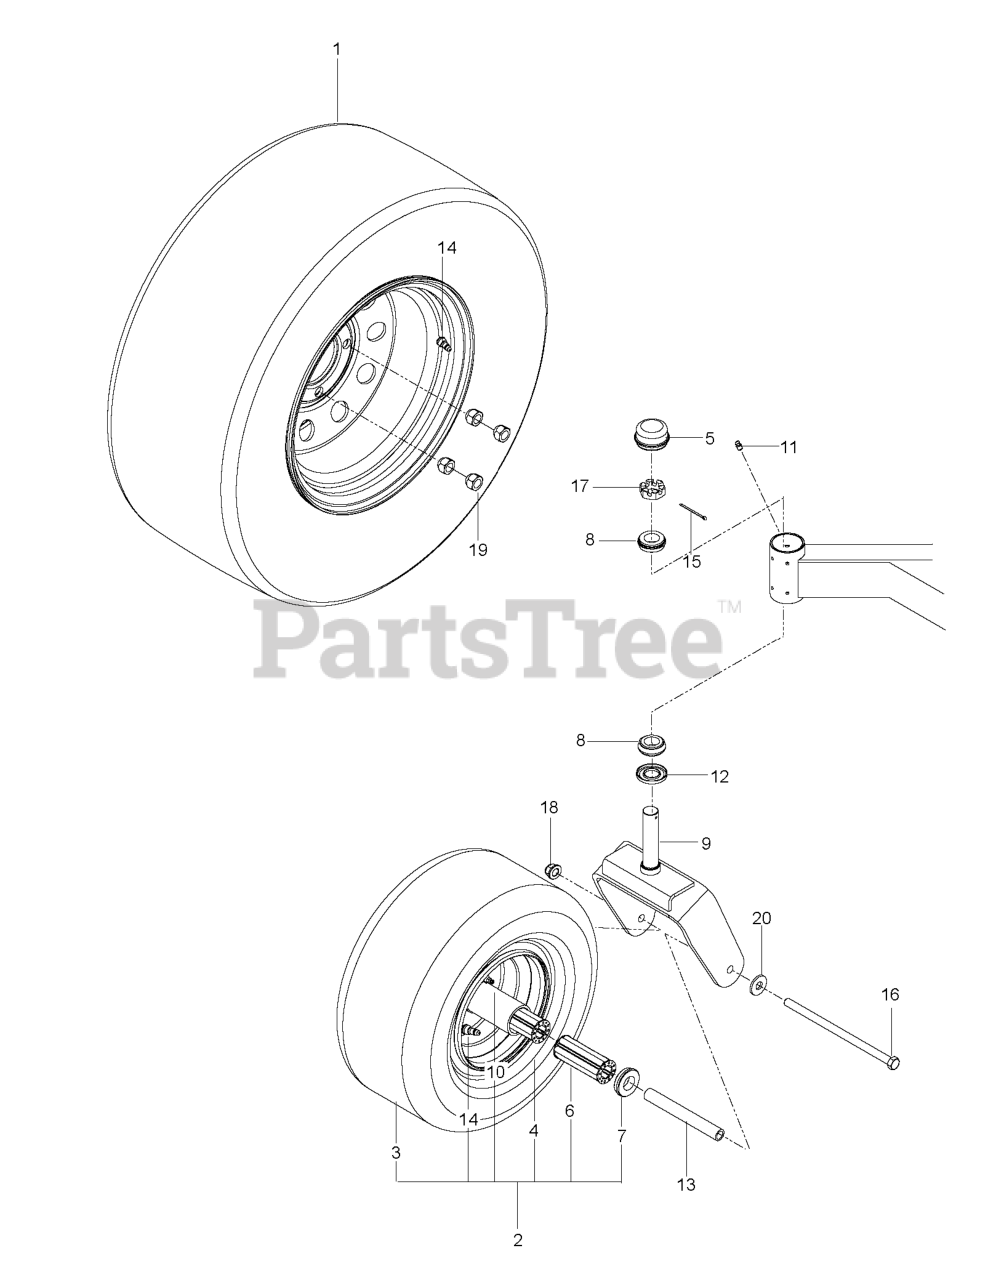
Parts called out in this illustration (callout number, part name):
1	WHEEL.ASSEM.22X10-10.SILVE.ZTR
2	TIRE.ASSEM.CASTER.13X6.5-6.SIL
3	TIRE.13X6.50-6.4.PLY
4	WHEEL.6X4.50.CASTER.SILVER
5	GREASE CAP
6	ROLLER BEARING-CAGED 3 1/4'
7	BEARING RETAINER
8	TAPERED ROLLER BRG
9	YOKE.CASTER.ORANGE
10	ZERK
13	SPACER, PIVOT
14	VALVE STEM TR-412
15	COTTER PIN 1/8 X 2
16	HEX SCREW 1/2-13 X 9.5 GR5
17	NUT 1"C HEX SLOTTED
18	NUT, 1/2-13 HEX FLG NYLOC ZD
19	LUG NUT 1/2F
20	WASH USS FLAT 1/2
